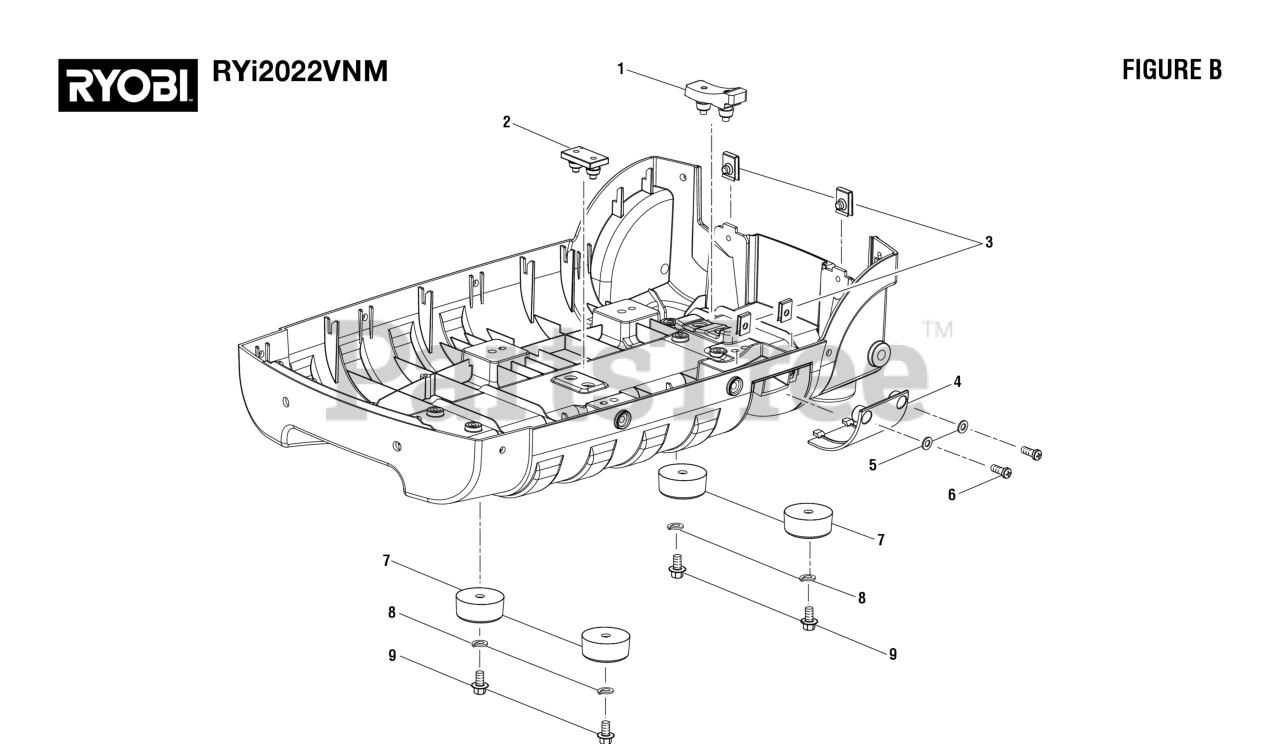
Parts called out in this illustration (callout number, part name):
1	Engine Support Isolator (Back)
2	Engine Support Isolator (Front)
3	U-Clip (M5)
4	Oil Drain Door
5	Washer (ID5.3 x OD10 x 1t)
6	Screw (M5 x 12 mm, Phillips Pan Hd)
7	Isolator Foot
8	Lock Washer (1/4 in.)
9	Bolt (M6 x 12 mm, Hex Hd.)
